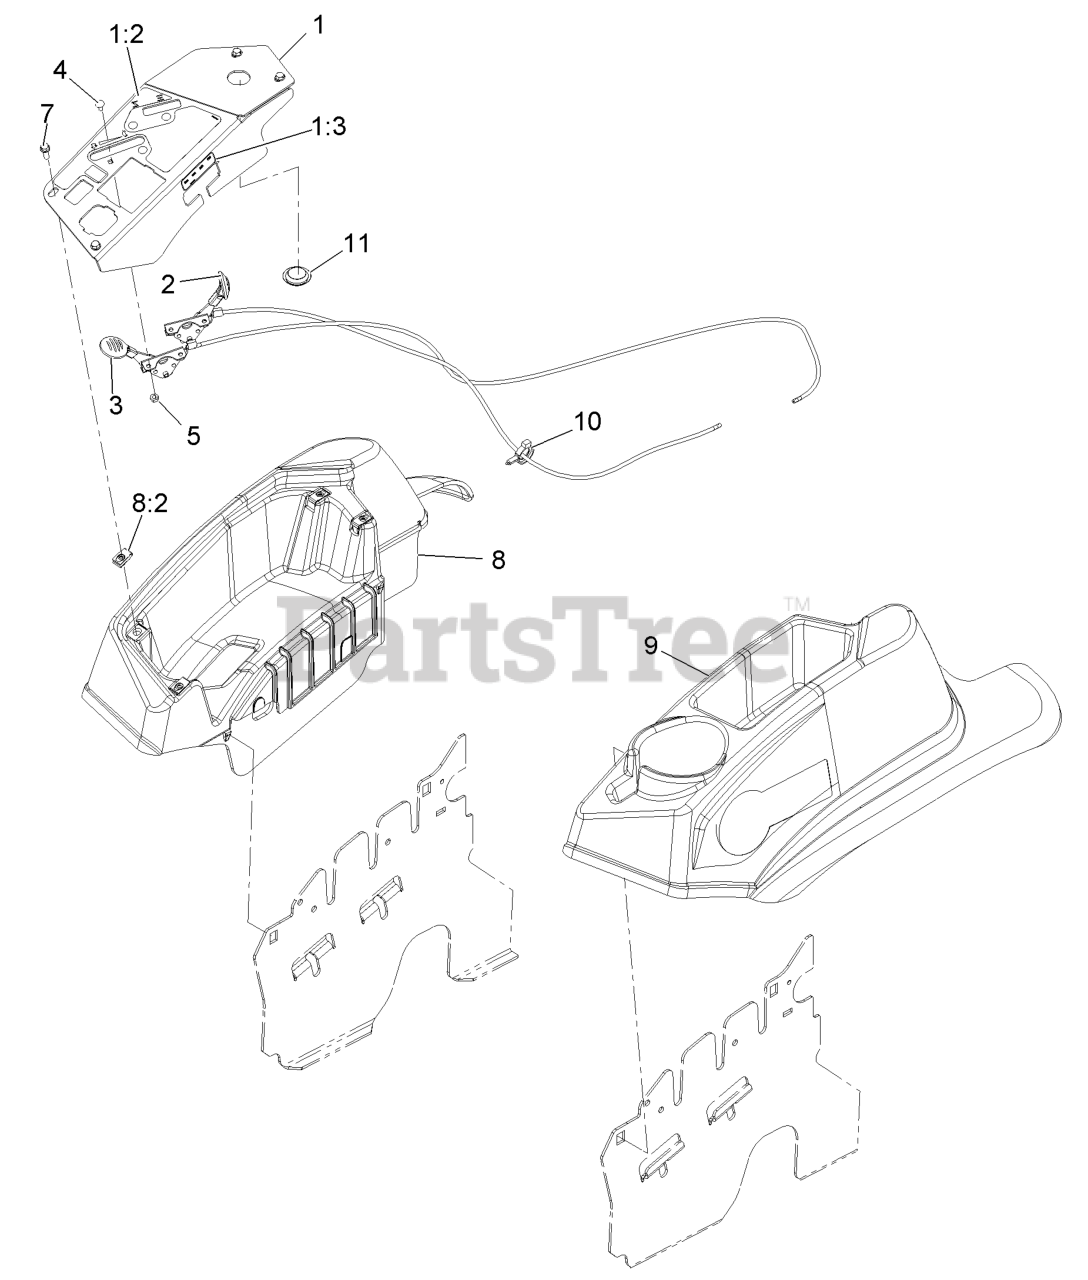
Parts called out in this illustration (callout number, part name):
1	ASM,CONSOLE PANEL W/DECAL
1:2	DECAL-CONTROL PANEL
1:3	DECAL-FUSE
2	ASM, CHOKE CABLE
3	ASM,THROTTLE CABLE
4	BOLT-CARR
5	NUT-LOCK, NI
7	SCREW-HWH
8	CONSOLE,RH AS ASM
8:2	Nut-Retainer-Panel 1/4-20
9	CONSOLE, LH AS
10	CLAMP-HOSE
11	PLUG-PLASTIC
